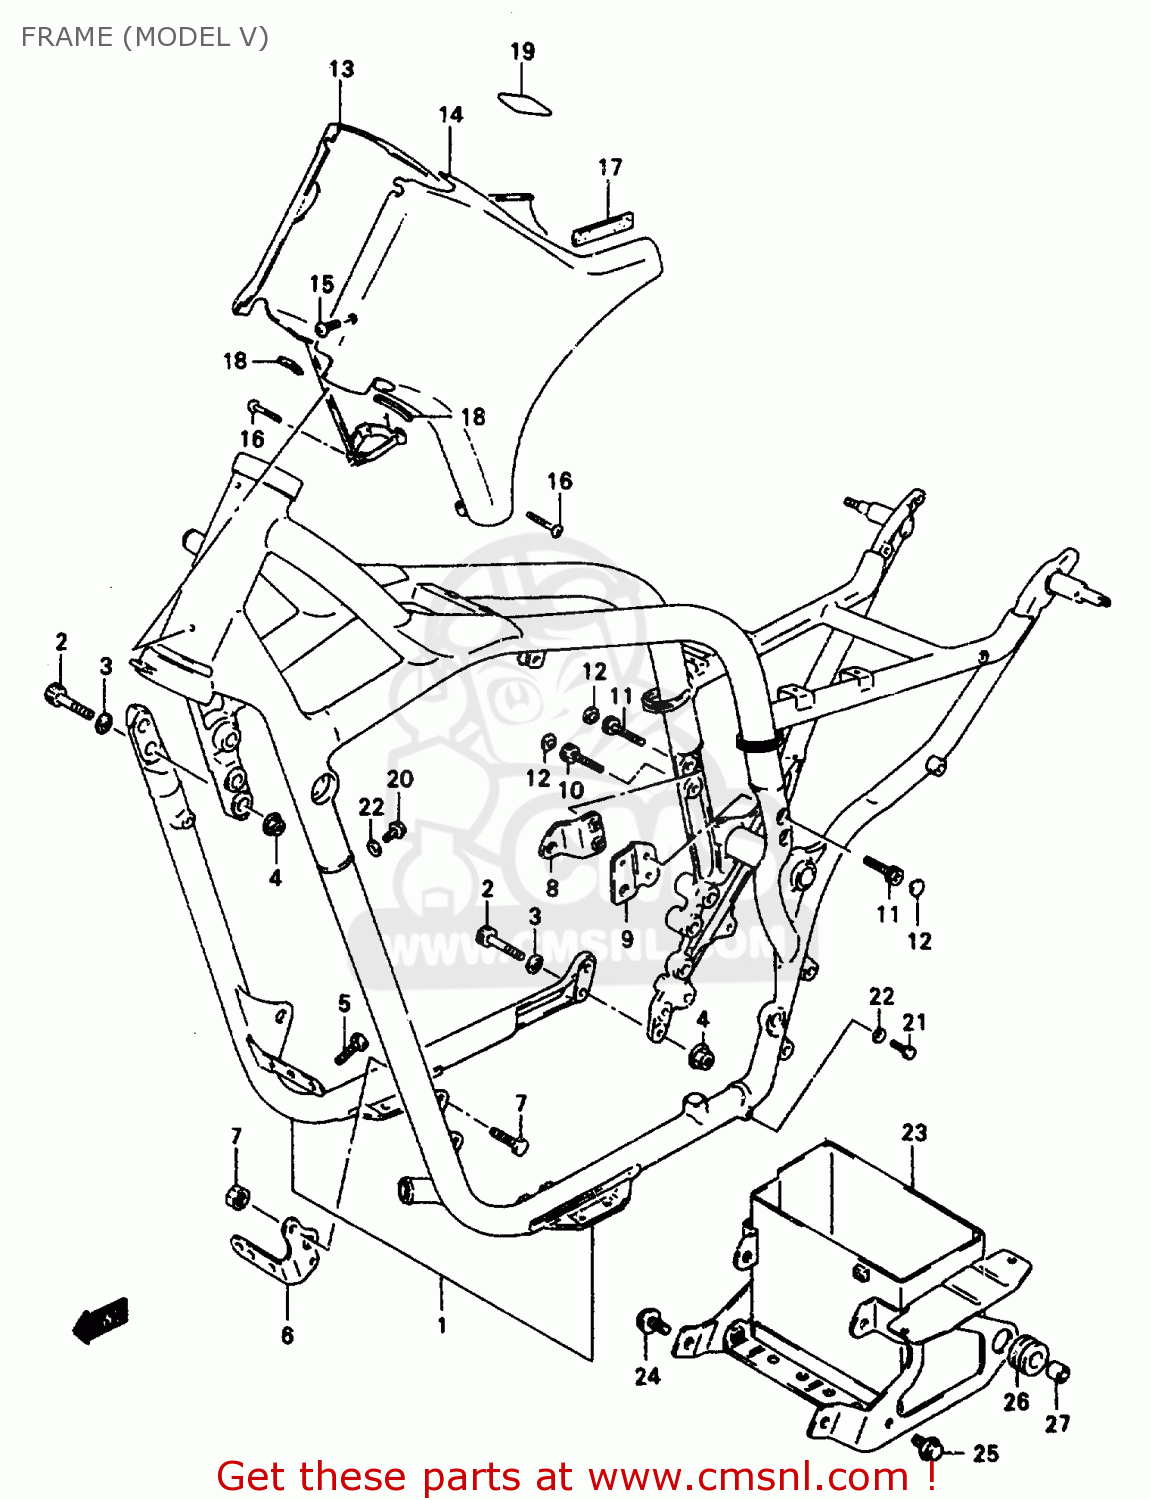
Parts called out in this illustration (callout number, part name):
1	FRAME SET
2	BOLT(10X33)
3	WASHER
4	NUT 10MM
5	BOLT
6	PLATE,ENGINE MOUNT NO.1,L
7	BOLT, UPPER
8	PLATE,ENGINE MOUNT NO.3,R
9	PLATE,ENGINE MOUNT NO.3,L
10	PLATE,ENGINE MOUNTING NO
11	BOLT
12	BOLT(8X30)
13	CAP(OD:14.5)
14	COVER,FRAME HEAD,RIGHT
15	COVER,FRAME HEAD,LEFT
16	SCREW
17	SCREW
18	MOLDING
19	MOLDING,FUEL TANK
20	UNION
21	BOLT
22	BOLT
23	HOLDER,BATTERY
24	BOLT
25	BOLT
26	BOLT
27	BUSH
28	BUSH
